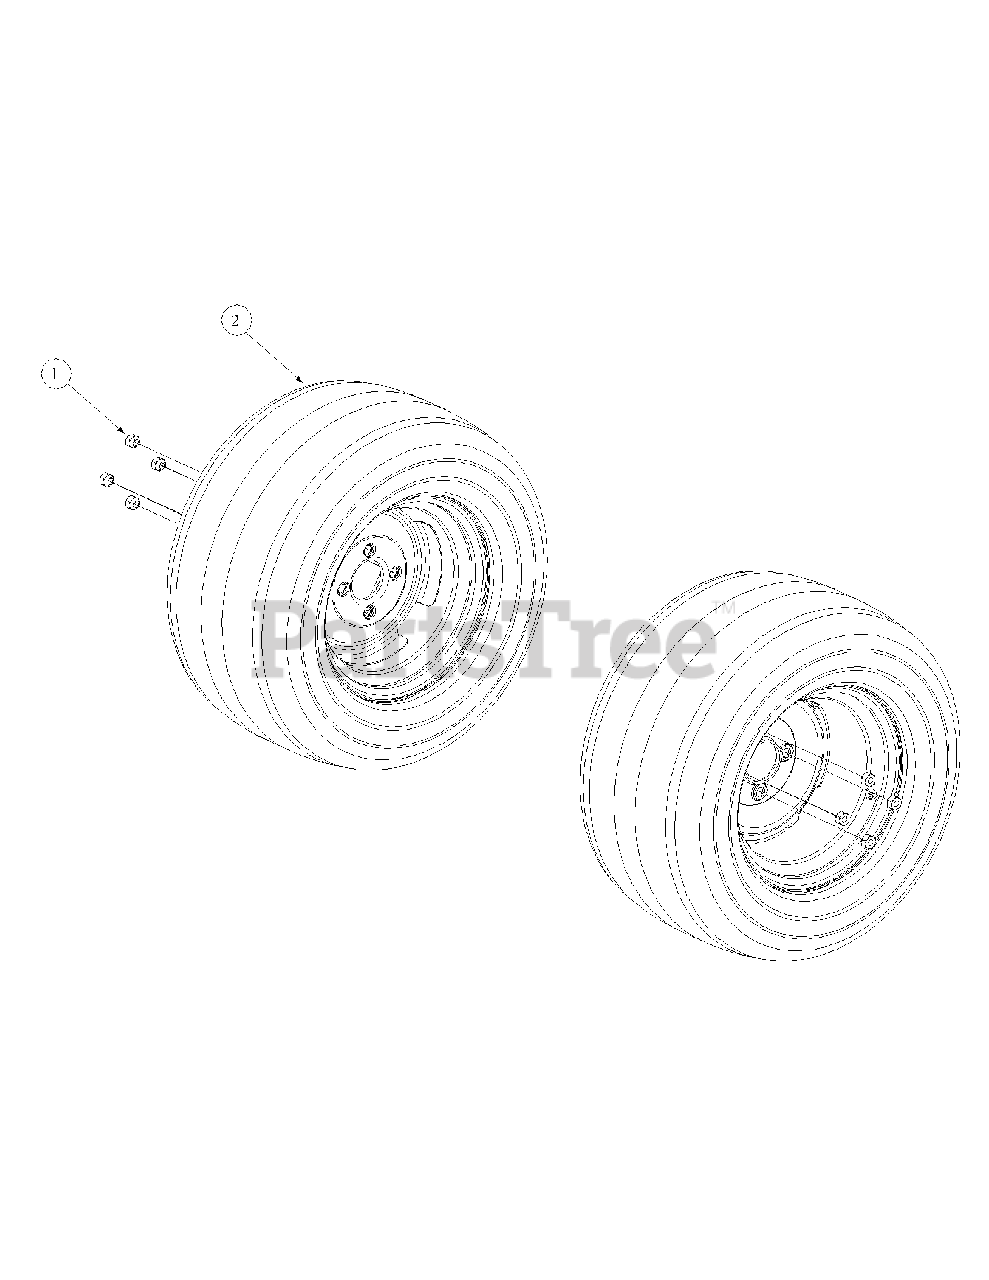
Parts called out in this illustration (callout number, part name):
1	Lug Nut, 1/2-20
2	Wheel Assembly, 23 x 9.5-12, Dr, White:
2	Tire, Turf Master, 23 x 9.50-12, 2-Ply
2	All Trail, Rear Tire
2	Wheel Assembly, 24 x 12-8, Dr, White:
